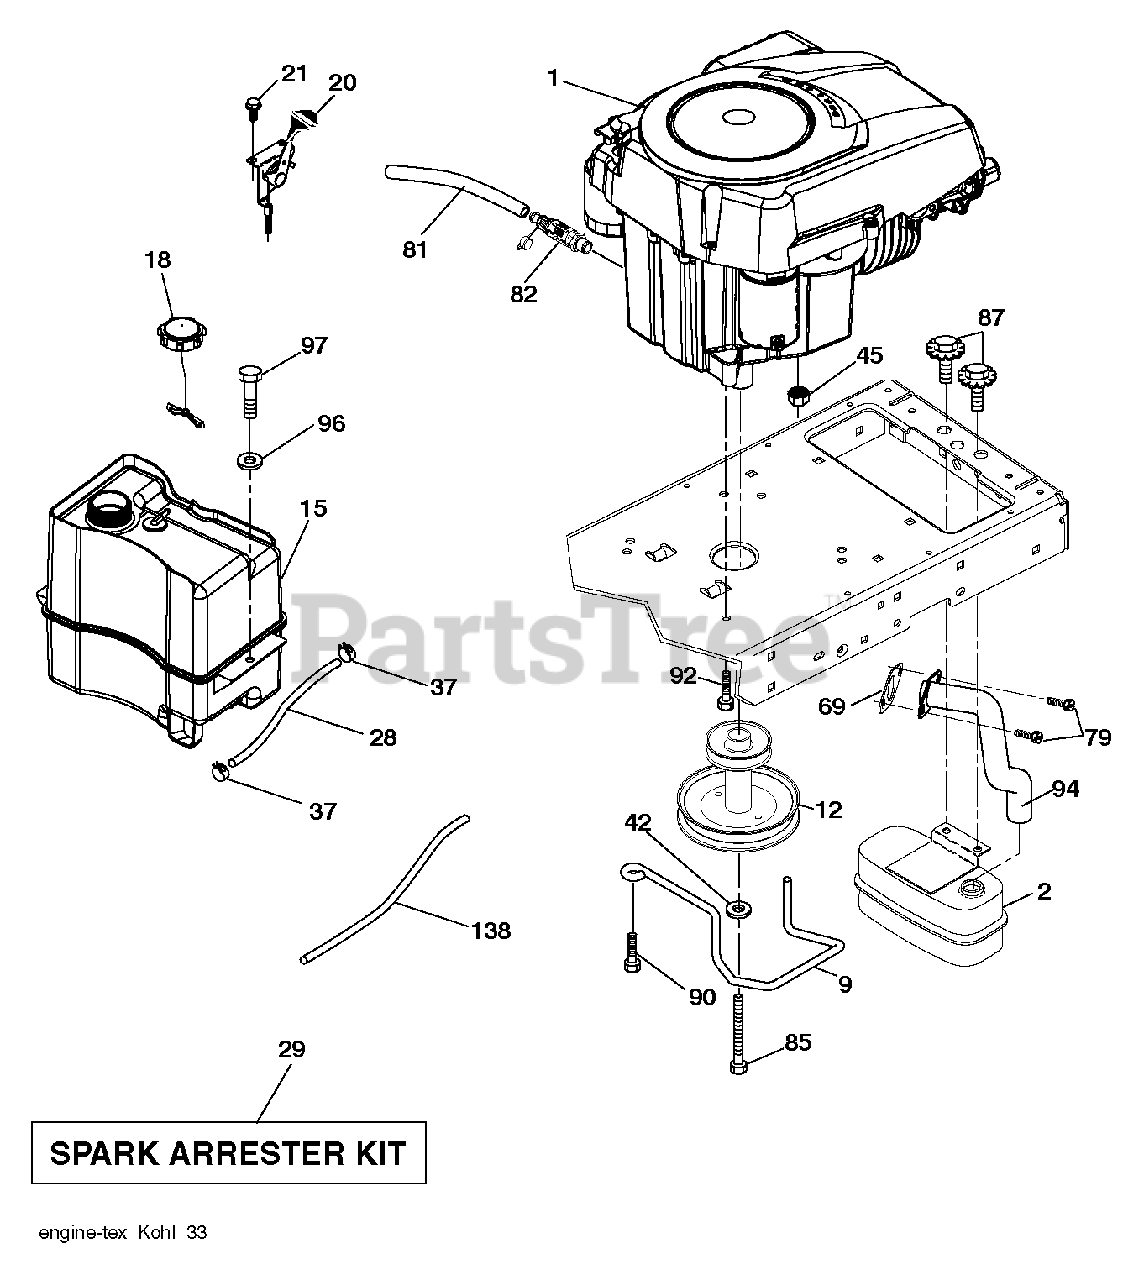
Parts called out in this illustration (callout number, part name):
9	KEEPER.BELT.ENGINE.4.2
21	SCREW.#10 X 0.750.BOS THREAD
29	ARRESTER SPARK (OPTIONAL)
37	HOSE CLAMP
42	LOCKWASHER
79	SCREW.SOCKET HD.5/16-1
81	TUBE, DRAIN OIL ASM.
82	VALUE.OIL.DRAIN
87	BOLT, 5/16-18 X 1 3/4
90	SCREW 3/8-16X1
92	SCREW 3/8-16X1
97	SCREW HEXWSHR 1/4-20X3/4
